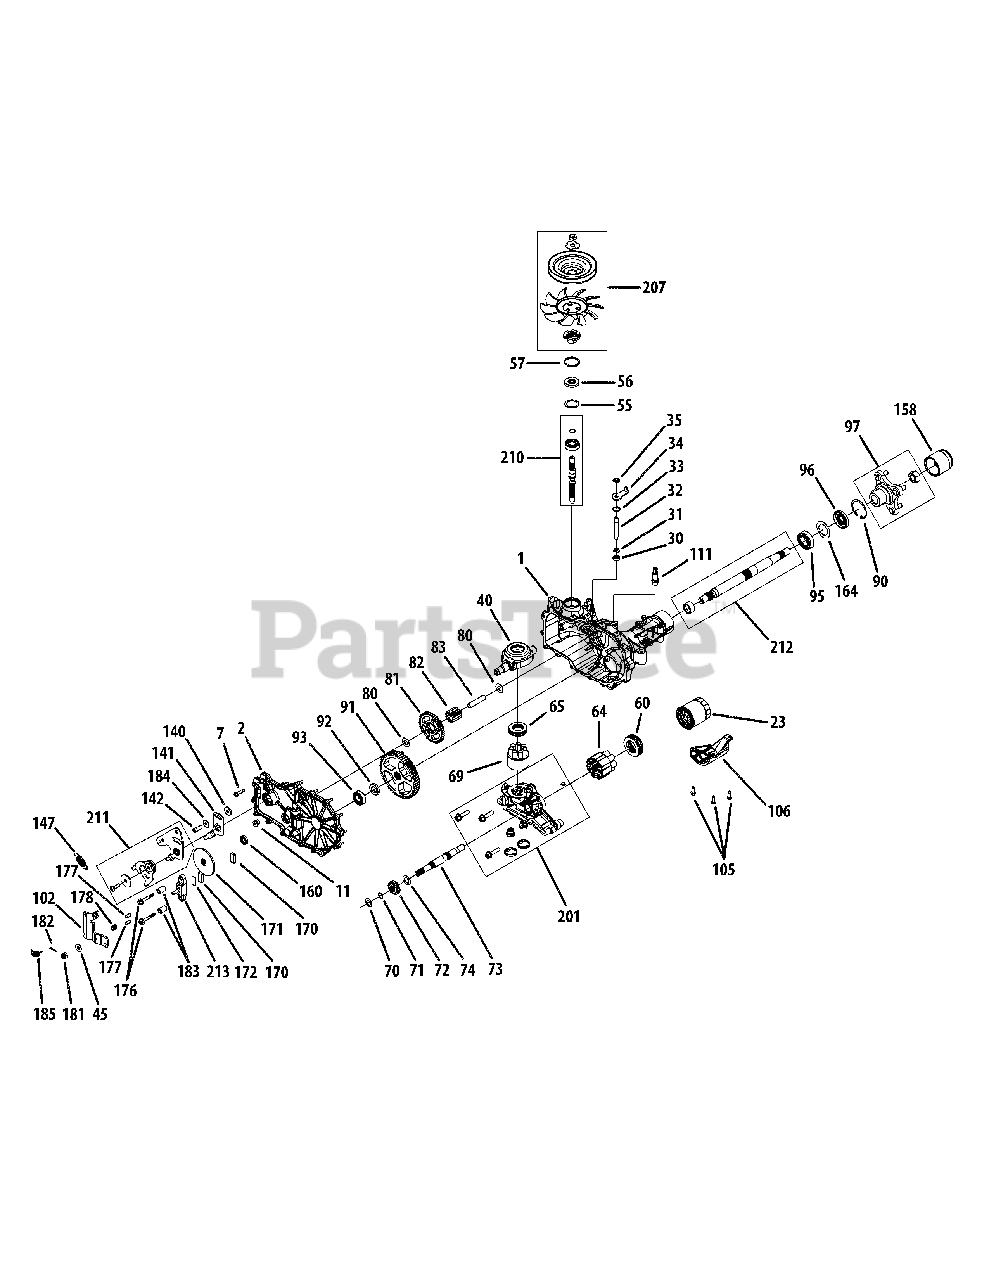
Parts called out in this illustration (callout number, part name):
1	Kit, Housing, Main, RH
2	Kit, Cover Side RH Control
7	Screw, Hex Washer
23	Filter, Spin-On 2.6 x 3.0
30	Seal, Lip, .375 x .75 x .25
31	Ring, Retaining .375 External
32	Rod, Bypass
33	Ring Retaining .750 Internal
34	Arm, Bypass
35	Ring, Ret .375 External
40	Trunnion, Swashplate
45	Washer, .34 x .88 x .06
55	Washer, 1.23 x 1.57 x .04
56	Seal, Lip 17 x 40 x 7
57	Ring Retaining Internal
60	Bearing, Thrust 35 x 62 x 18
64	Kit, 16cc Cylinder Block Assembly
65	Thrust Bearing, 30 x 52 x 13
69	Kit, Block, 7 Piston
70	Washer, .63 x 1.00 x .05
71	Ring, Reatining, Motor Shaft
72	Gear, 16T
73	Shaft, Motor
74	Washer, .71 x 1.16 x .04
81	Gear, 43T
82	Gear, 11T
83	Pin, Jackshaft
90	Ring, Retaining 2.25 Internal
91	Gear, 54T
92	Spacer, .750 x 1.00 x .257
93	Bearing, Ball 3/4 x 40mm x 12mm
95	Bearing, Ball 25.4 x 52 x 15
96	Seal, Lip, 1.0 x 2.06 x .38
97	Kit, Hub 4-Bolt
102	Arm, Brake
105	Screw, Hex Washer 1/4-20 x .75
106	Guard, Filter, RH
111	Kit, Fitting 1/2 Beaded 9/16 SAE
140	Spacer, .320 x 1.005 x .150
141	Arm, Return Left
142	Socket Cap Screw, 5/16-24 x 7/8
147	Spring, Extension
158	Cap, Axle
160	Seal, Lip .625 x 1.00 x .250
164	Spacer, 1.355 x 2.035 x .021
170	Puck, Brake
171	Rotor, Brake
172	Puck, Plate
176	Screw, .250-20 x 2.0 HFS Patch
177	Pin, Brake Actuating
178	Compression Spring
181	Nut, Castle 5/16-24
182	Pin, Cotter 3/32 x 3/4
184	Washer, .34 x .88 x .06
185	Spring, Brake Arm Bias
201	Kit, Center Section RH
207	Kit, Fan Pulley
207	Fan Only
207	Pulley Hub
210	Kit, Input Shaft
211	Kit, RTN Bidirectional
212	Kit, Shaft Axle
213	Kit, Brake Yoke
